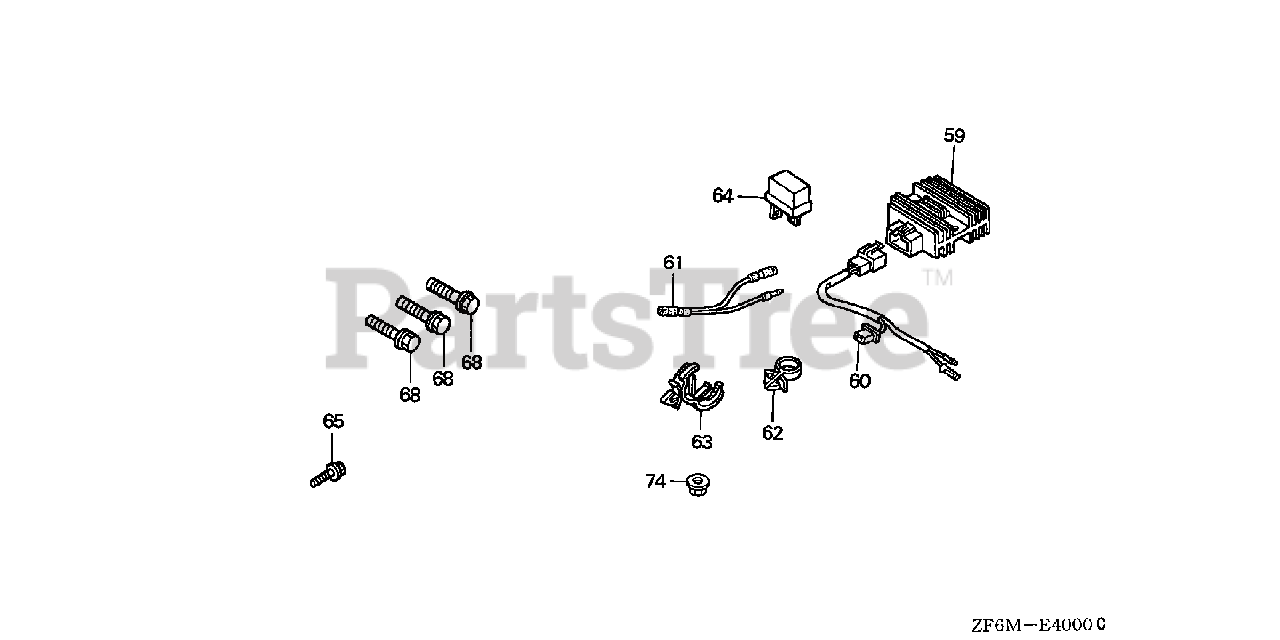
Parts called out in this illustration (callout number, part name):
59	RECTIFIER ASSY., REGULATOR
60	SUB-WIRE HARNESS ASSY.
61	SUB-HARNESS
62	HOLDER, STOP SWITCH WIRE
63	CLIP, WIRE HARNESS
